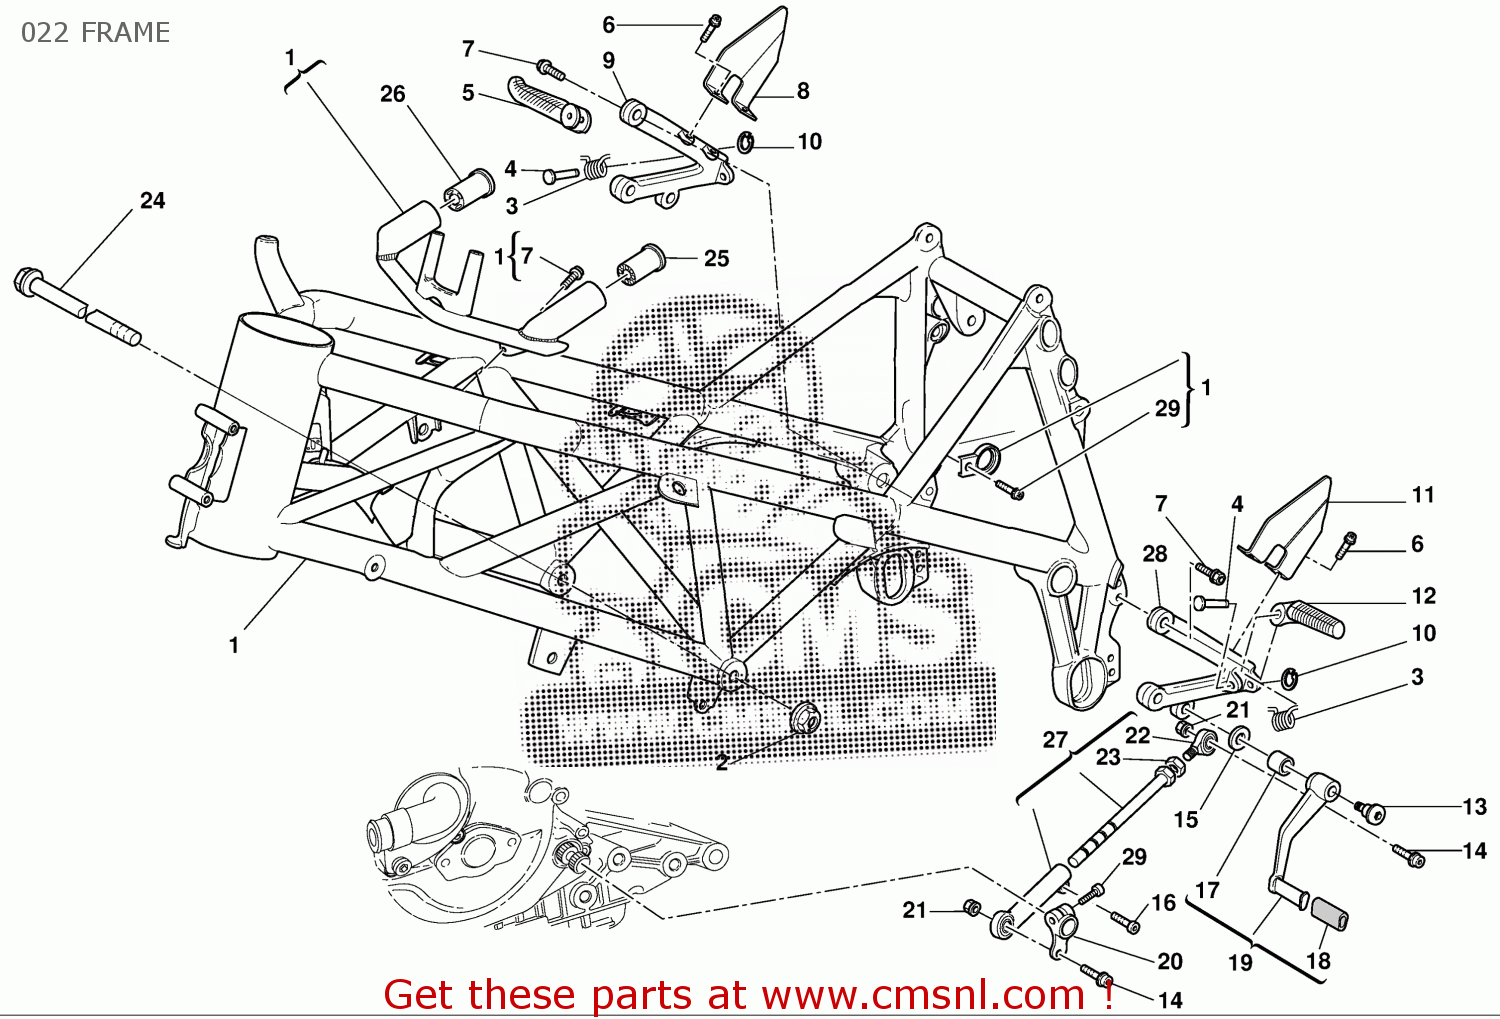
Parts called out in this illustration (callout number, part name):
1	FRAME 999 R/03
2	NUT
3	SPRING. FOOTREST
4	FOOTREST PIN
5	FOOTREST, FRONT RH
6	SCREW TCEIF M5X8
7	SCREW TCEIF M8X20
8	GUARD FRONT STEP RH
9	BRACKET FRONT RIGHT FOOTREST
10	CIRCLIP E-TYPE
11	GUARD FRONT STEP LH
12	FOOTREST, FRONT LH
13	PIN PEDAL
14	SCREW TCEIF M6X20
15	WASHER
16	SCREW TCEIF M6X16
17	BUSH
18	RUBBER PAD
19	PEDAL, GEAR CHANGE
20	GEAR CHANGE ARM
21	NUT, SELF-LOCKING M6
22	BALL JOINT, RIGHT
23	NUT 6MM
24	SCREW
25	RUBBER PAD
26	RUBBER PAD
27	ROD, GEAR SHIFT LINK
28	BRACKET FRONT LEFT FOOTREST
29	SCREW TCEIF M6X18
